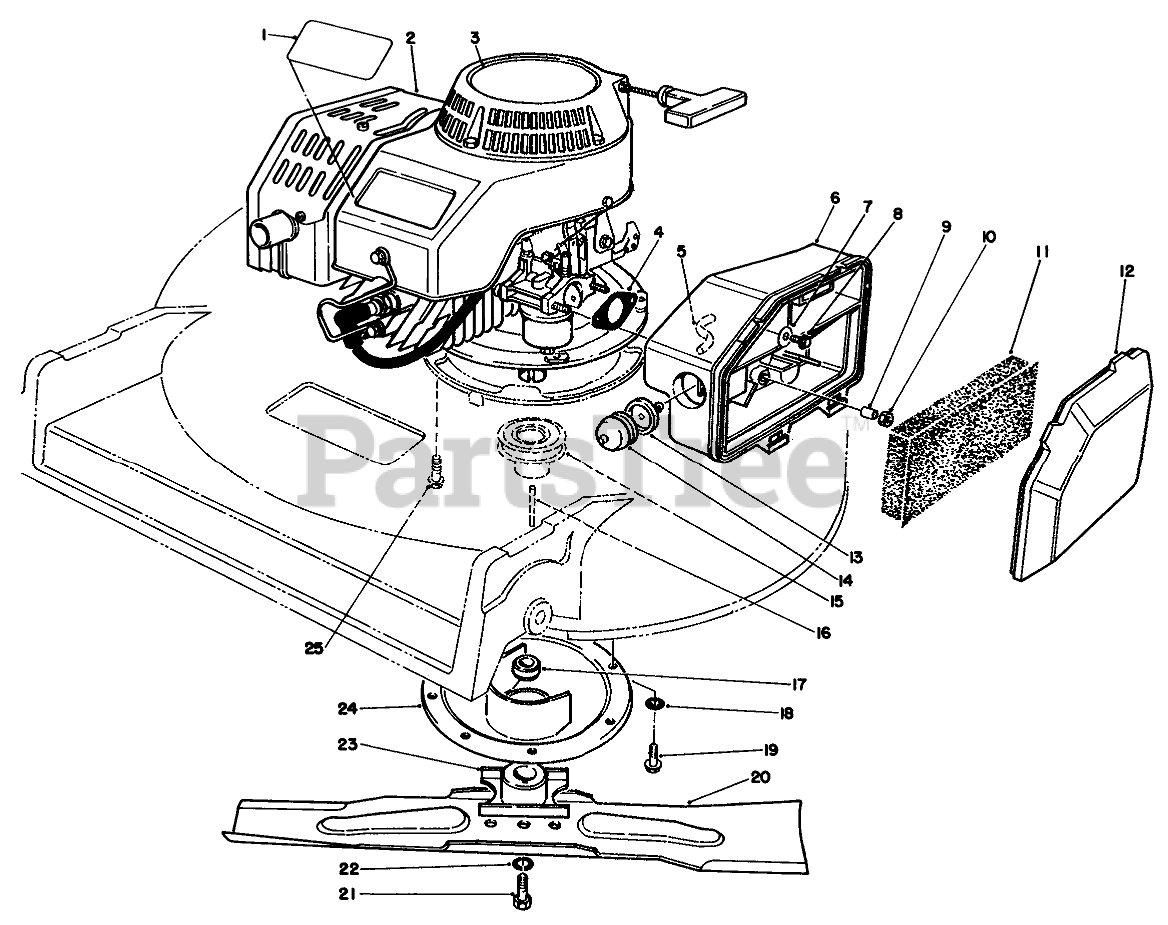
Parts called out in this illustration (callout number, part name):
1	DECAL - PROLINE
2	ENGINE ASM
3	DECAL-2 CYC RECOIL COMM
4	GASKET-AIR CLEANER
5	HOSE-PRIMER
6	BODY-AIR CLEANER
7	WASHER-FLAT
8	SCREW-HH
9	SPACER
11	ELEMENT-AIR CLEANER
12	COVER-AIR CLEANER
13	BODY-PRIMER
14	BULB-PRIMER
15	PULLEY-DRIVER
16	KEY-SQUARE
17	SPACER-BLADE RETAINER
18	WASHER-LOCK, INTERNAL
19	SCREW-HWHTF
20	Key
21	SCREW-BLADE
22	WASHER-LOCK
23	RETAINER-BLADE
24	PROTECTOR-CRANKSHAFT
25	SCREW-HHF
